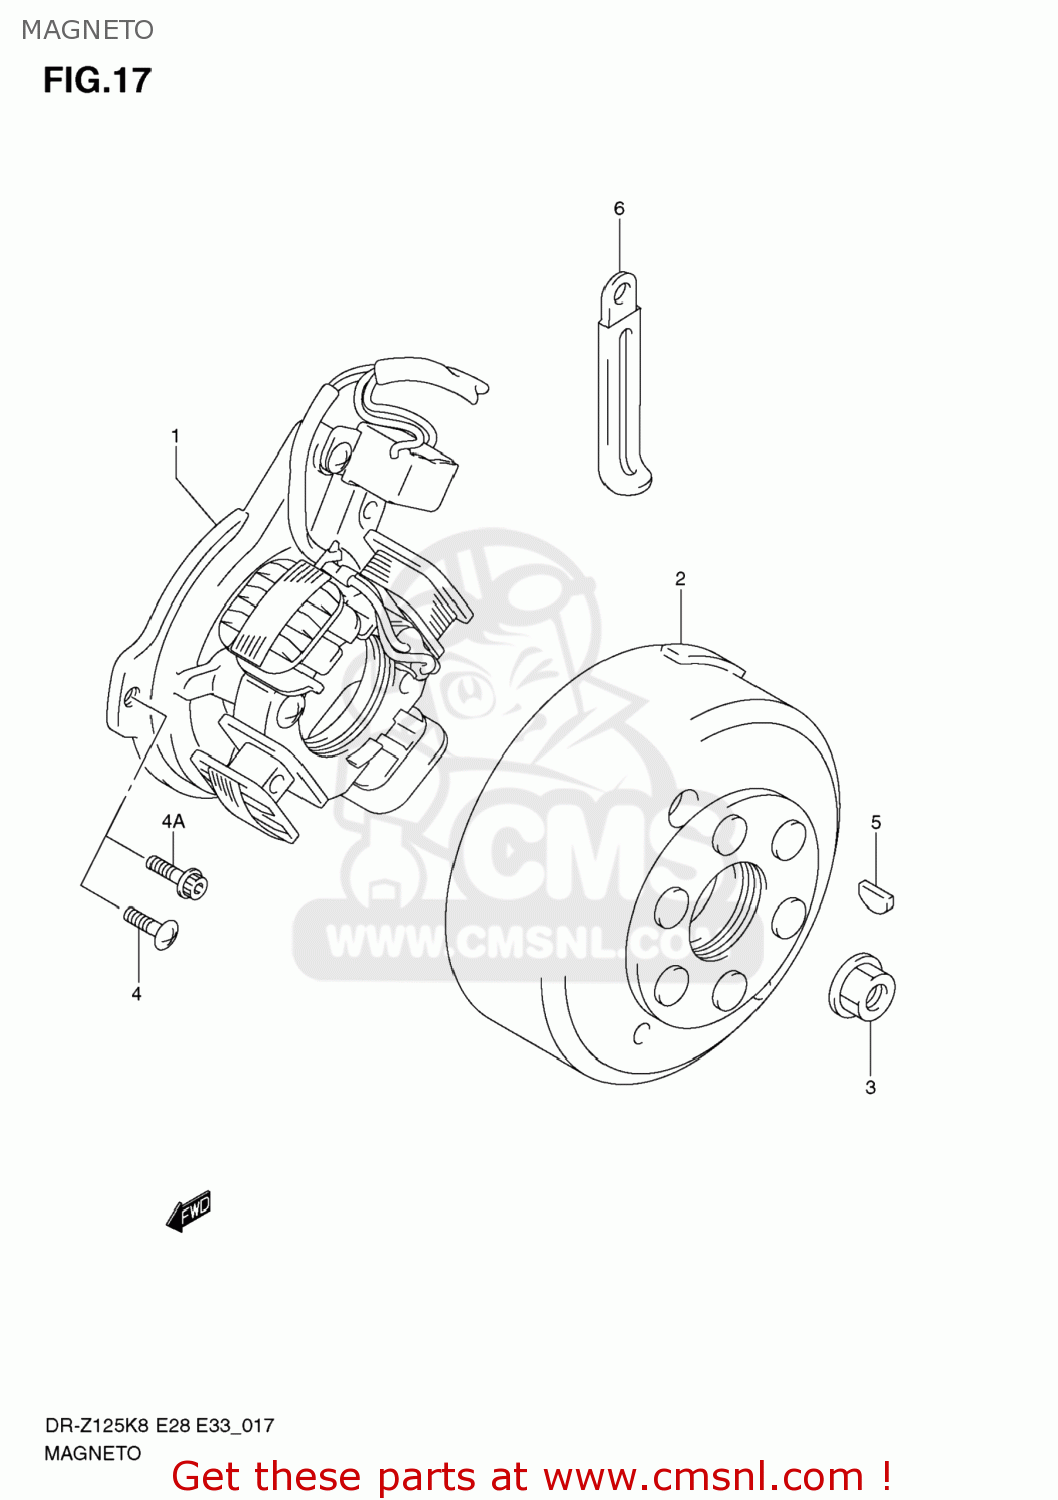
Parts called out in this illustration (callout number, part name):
1	STARTER ASSY
2	ROTOR ASSY
3	NUT
4	SCREW
4A	BOLT
5	KEY
6	CLAMP(L:80)
